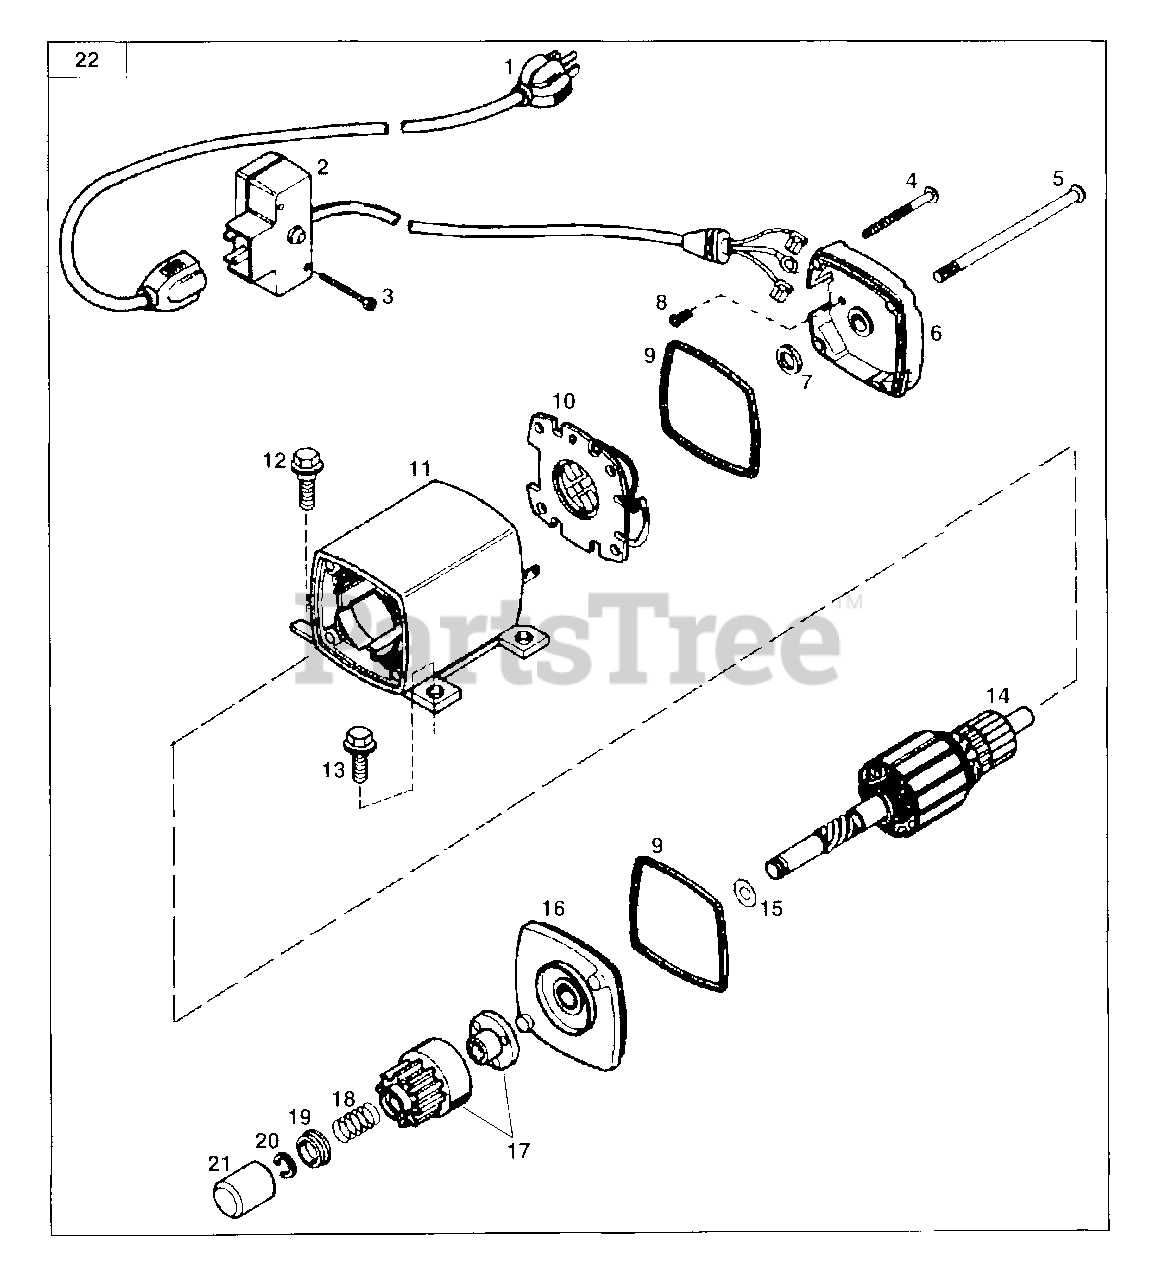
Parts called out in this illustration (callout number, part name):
1	Extension Cord (10'6")
2	Switch Box Ass'y.
3	Screw, 6-32 x 2 1/2"
4	Ground Screw
5	Case Bolt
6	Commutator End Cap Ass'y
7	Thrust Washer
8	Ground Screw
10	Brush Card Ass'y
11	Housing Ass'y
12	Screw, 1/4-20 X 1/2"
13	Screw, Torx T-30, 1/4-20 X 1/2"
15	Thrust Washer
16	Drive End Cap Ass'y.
17	Gear & Nut
18	Anti-drift Spring
19	Spring Retainer
20	Retainer Ring
21	Dust Cover
22	Electric Starter Assembly
